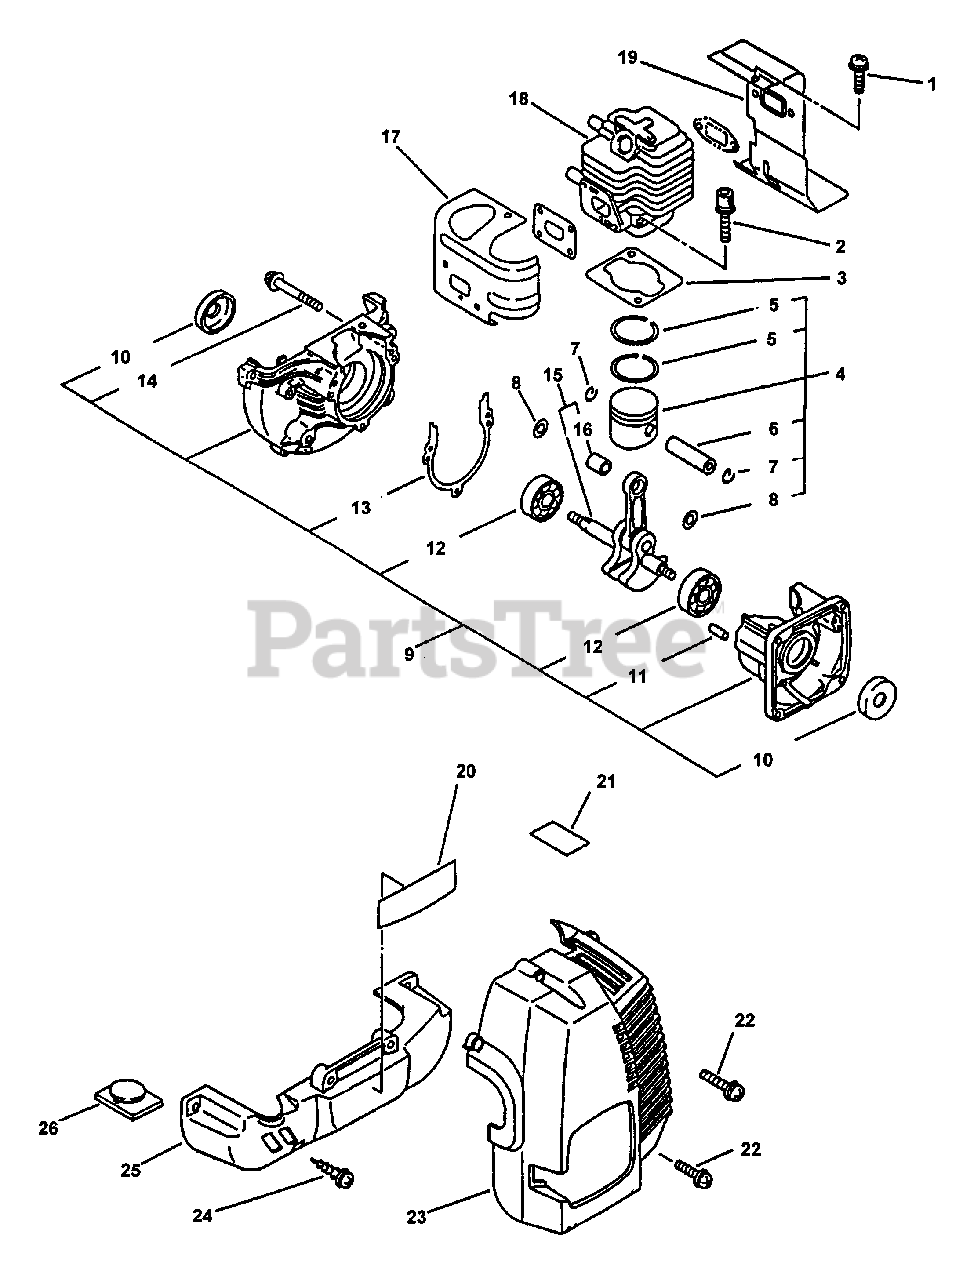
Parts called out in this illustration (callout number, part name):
1	SCREW - 5X10
2	SCREW - 5X22
3	GASKET, CYLINDER
4	PISTON KIT
5	RING, PISTON
6	PIN, PISTON
7	RING, RETAINING
8	SPACER, PISTON
9	CRANKCASE KIT
10	SEAL, OIL
11	PIN - LOCATING
12	BEARING, BALL - 6201
13	GASKET KIT
14	SCREW - 5X28
15	CRANKSHAFT ASSY
16	BEARING, NEEDLE
17	COVER, CYLINDER - INTAKE
18	CYLINDER
19	COVER, CYLINDER - EXHAUST
20	LABEL - MODEL
21	LABEL - HOT SURFACE
22	SCREW - 5X16
23	COVER, ENGINE
24	SCREW - 5X20 -- TAPPING
25	COVER
